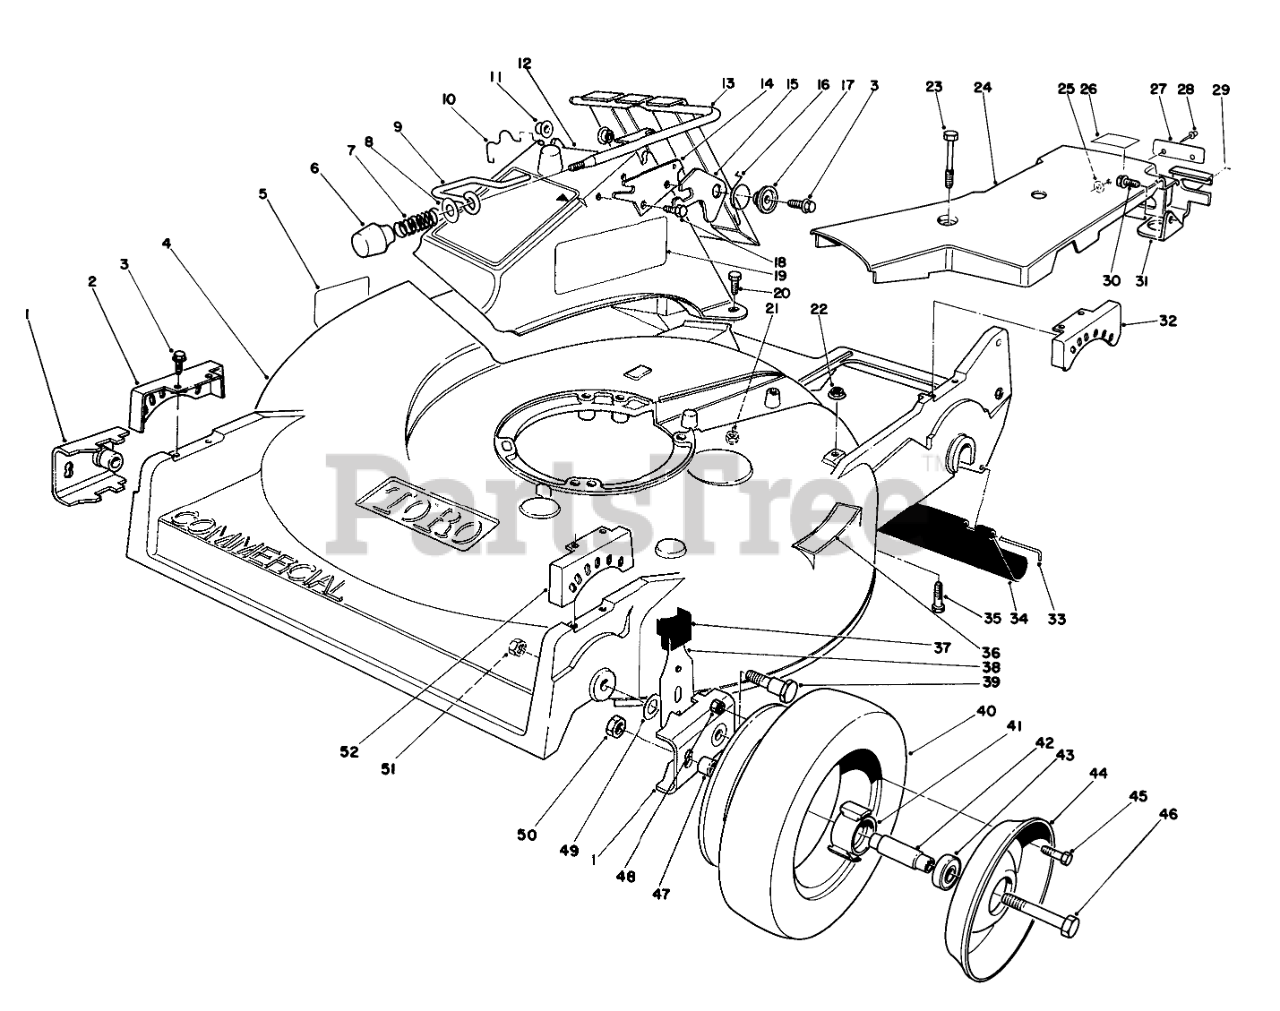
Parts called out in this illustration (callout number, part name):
1	PIVOT ARM
2	QUADRANT-FRONT, RH
3	Screw
4	Housing (Incl. Ref. #5 & 36)
5	DECAL-DANGER
7	COMPRESSION SPRING
8	WASHER-FLAT
9	DOOR LATCH
10	DOOR RETAINER
11	BUSHING-NYLON
12	DISCHARGE CHUTE B
13	DOOR & HANDLE WA
14	DOOR LATCH PLATE
15	SAFETY LATCH
16	TORSION SPRING
17	DOOR SPACER
18	SCREW-HWH
19	DECAL SAF INST
20	SCREW-HH
21	NUT-LOCK, NI
22	NUT-HF
23	SCREW-HHFTF
24	Belt Cover Assembly (Incl. Ref. #25 & 27-28)
25	WASHER-PLAIN
26	LABEL-GREASE
27	NAMEPLATE-GRD SPEED
29	RETAINER-CABLE
30	SCREW-HWHTF
31	Bracket-Traction Adj.
32	QUADRANT-REAR, LH
33	ROD-SHIELD
34	SHIELD-TRAILING
35	SCREW-HH
36	STEP PAD DECAL
37	KNOB-ARM
38	SPRING ARM ASM-FRONT
39	PIVOT SCREW
41	HUB-BEARING
42	SPACER-BEARING
43	BEARING-WHEEL
44	Wheel-Half
45	SCREW-HHF
46	SCREW-HH
47	SPACER-WHEEL
48	NUT-LOCK, NI
49	WASHER-PIVOT
50	NUT-LOCK, CONE
51	NUT-LOCK, NI
52	QUADRANT-FRONT, LH
